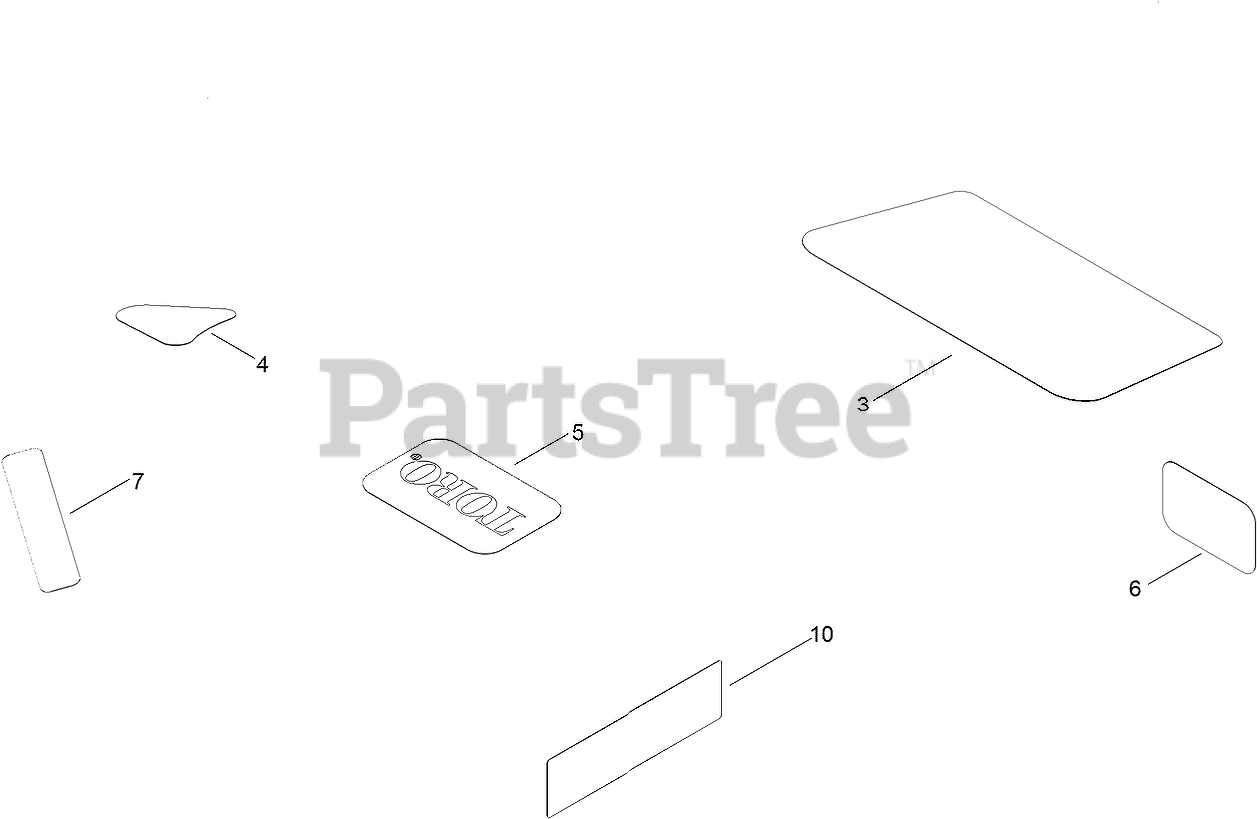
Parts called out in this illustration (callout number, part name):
3	DECAL-ENGINE
4	DECAL-DRAIN, OIL
6	PLACARD-INTAKE
7	DECAL-SHUTDOWN
